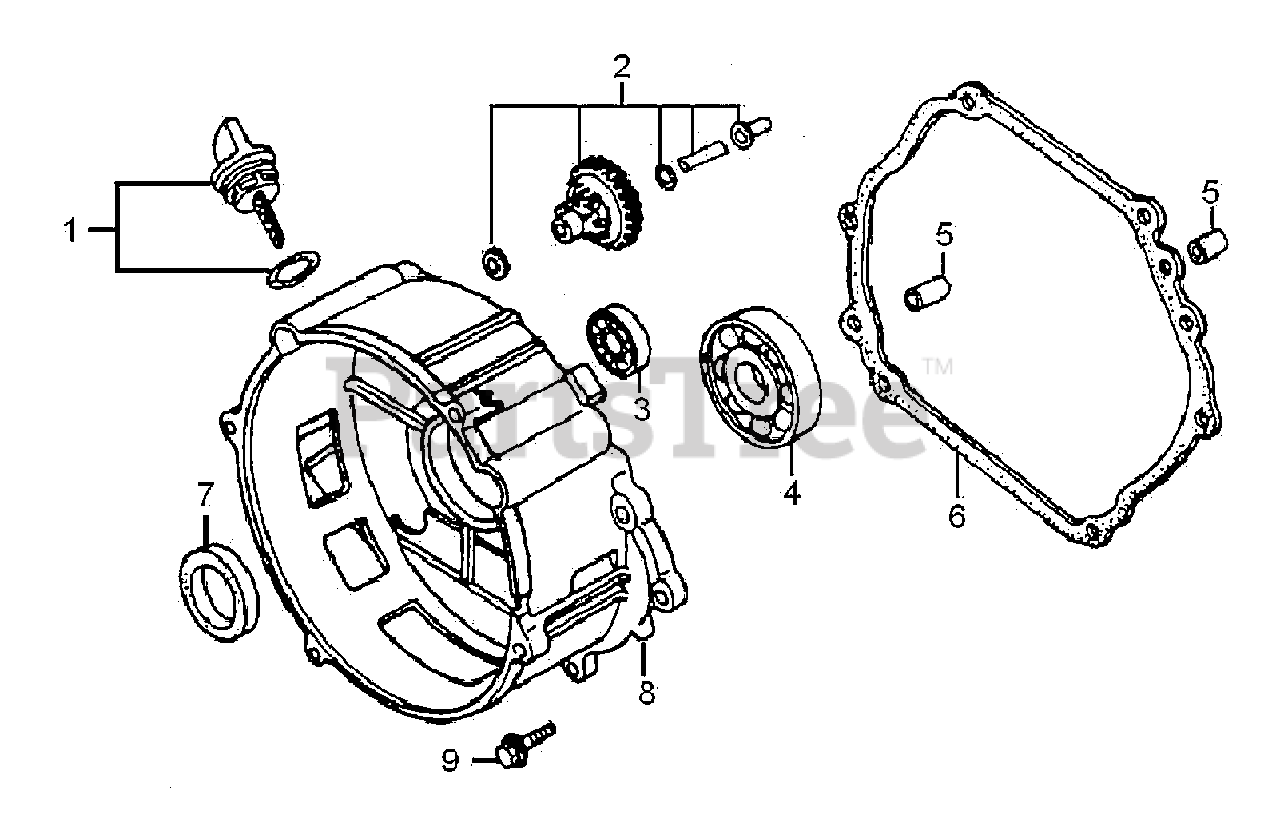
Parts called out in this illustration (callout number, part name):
1	CAP COMP.' OIL FILLER
2	GOVERNOR ASSY.
3	BEARING' RADIAL BALL 6207
4	BEARING' RADIAL BALL 6202
5	PIN' DOWEL 8×12
6	PACKING' CASE COVER
7	OIL SEAL 35×52×7
8	CRANKCASE COVER
9	BOLT' FLANGE M8×40
